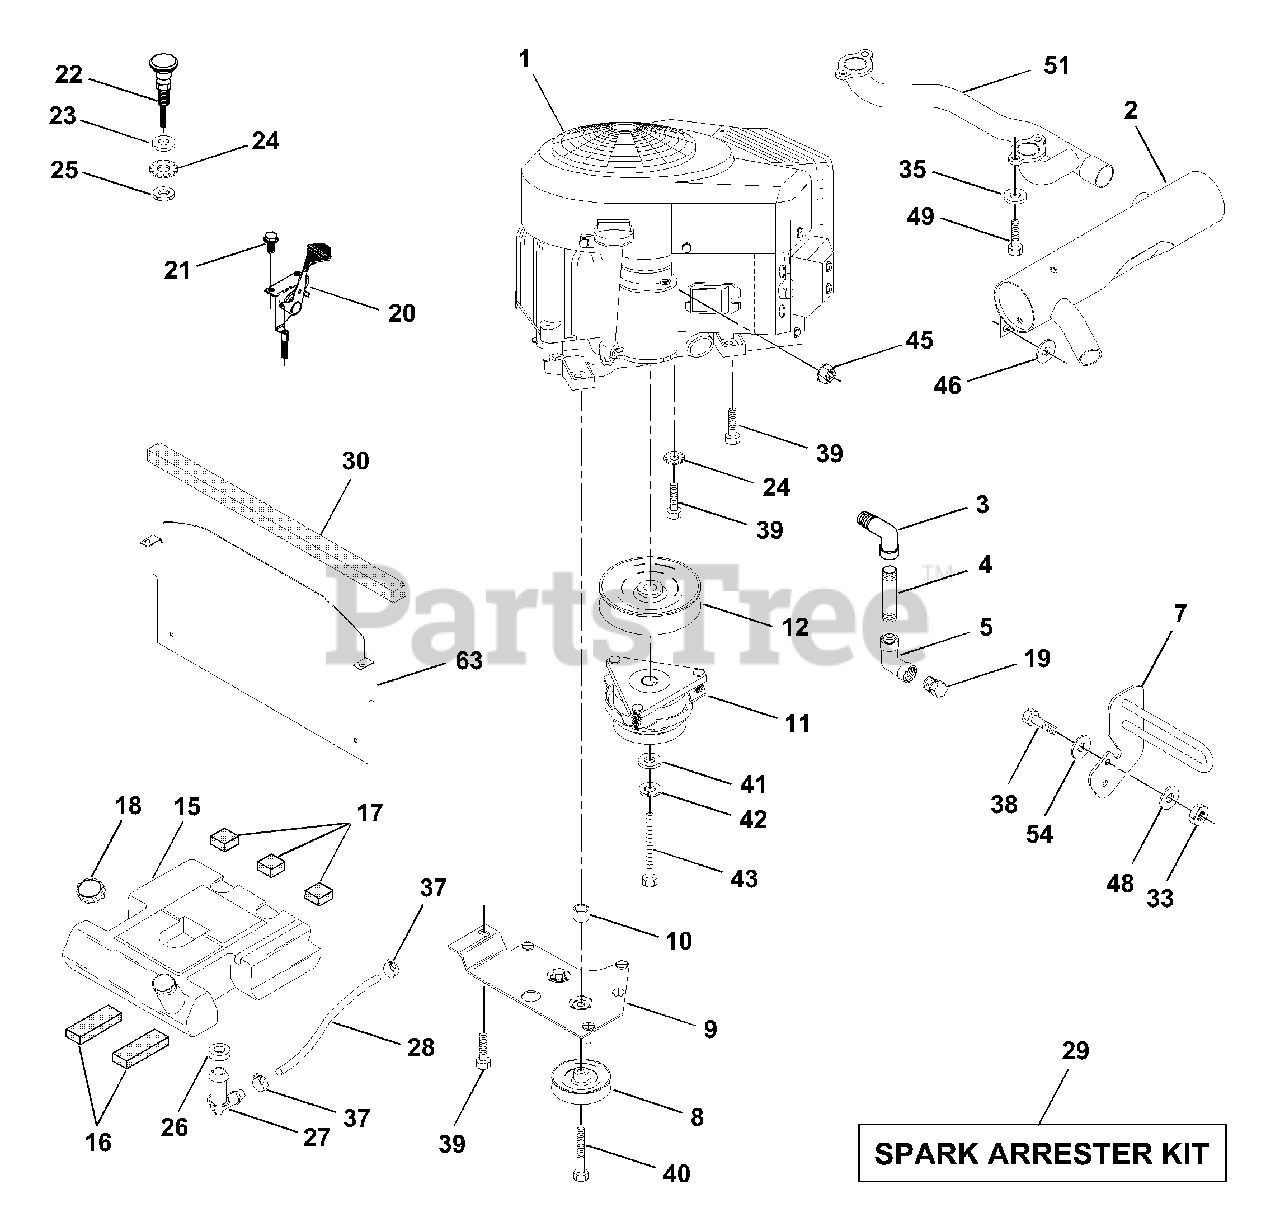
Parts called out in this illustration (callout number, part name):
2	Muffler VGT Cylinder
3	Elbow Street 3/8 NPT
4	Nipple Pipe 3/8NPT X 3 - 1/2
5	Elbow STD 90 Degree 3/8 - 18 NPT
7	Muffle Asm. Guard
8	Pulley V-Idler
9	Stop Keeper Asm VGT
11	Clutch Electric
12	Pulley Engine VGT Elect Clutch
15	Tank Fuel W/Sym Vented
16	Pad Spacer
17	Pad Spacer
18	Cap Asm Fuel W/Sym Vented
19	Plug Oil Drain
20	Control Throttle
21	Screw Hex Thd Cut 1/4 - 20 X 5/8
22	Control Choke
23	Washer 13/32 x 13/16 x 16 Ga.
24	Washer Ext Tooth 3/8
25	Nut Fin Hex 3/8 - 24 UNF
26	Bushing
27	Stem Tank Fuel
28	Fuel Line
29	Spark Arrester Kit
30	Strip Foam
33	Nut Lock Hex w/Ins 3/8 - 16
35	Washer Lock Hvy HLCL Spr 5/16
37	Clamp Hose
38	Bolt Fin Hex 3/8 - 16 x 1-1/2
39	Screw Thdrol 3/8 - 16 X 1 - 1/2 TT
40	Screw Thdrol 3/8 - 16 X 3 - 1/4
41	Washer 1-1/2 OD X 15/32 ID X .250
42	Washer Lock 7/16
43	Bolt Hex 7/16-20 X 4-1/4 Ga 5
45	Nut Keps Hex 1/4-20 UNC
46	Washer 13/32 x 1 x 16 Ga.
48	Washer 13/32 x 1-1/4 x 7 Ga.
49	Bolt Socket Hd 8 x 1.25 x 20 mm
51	Pipe Exhaust
54	Washer Flat 13/32 x 7/8 x 14 Ga.
63	Shield, Heat VGT HUSQ/Vanguard
